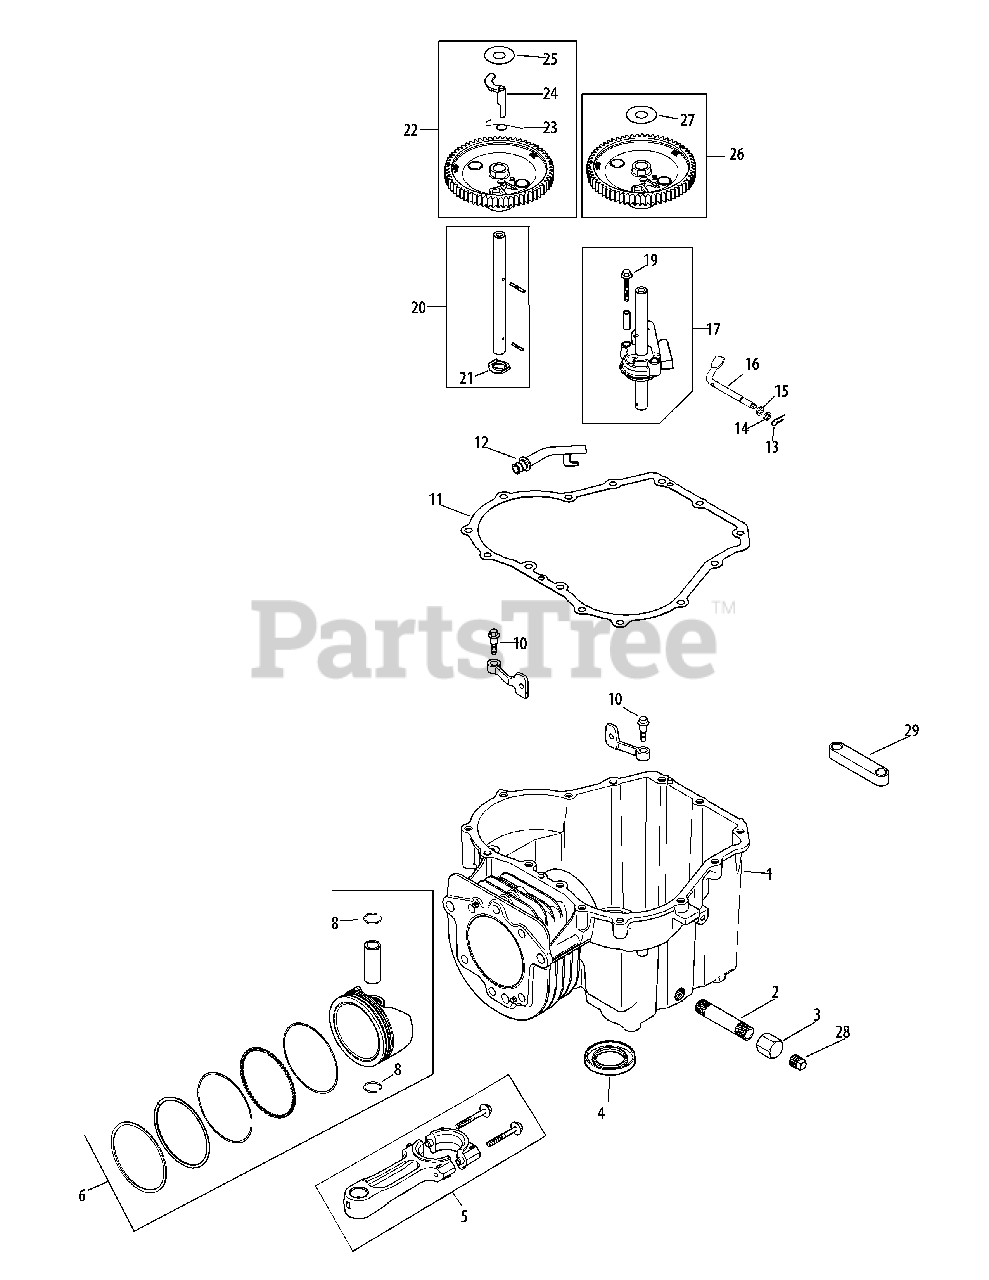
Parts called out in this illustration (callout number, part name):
1	Crankcase (Use: Short Block)
2	Not used in this application
3	Not used in this application
5	Connecting Assembly Rod
6	Piston w/ Ring Set, 94mm (Incl. 8)
8	Piston Pin Retainer
10	Shd. Thd. Frm. Screw, M6 X 1 X 26
11	Gasket
12	Drainback Tube
13	Hitch Pin Clip
14	Flat Washer, 6 Mm
15	Flat Washer, 1/4
16	Governor Cross Shaft
17	Oil Pump Ass’y Kit (Incl. 19)
19	Oil Pump Screw
20	Cam Center Shaft Kit (Incl. 21)
21	Thrust Washer
22	Camshaft Ass’y Kit (Incl. 23-25)
25	Thrust -Acr. Washer
26	Camshaft Ass’y Kit (Incl. 27)
27	Thrust -Acr. Washer
28	Square Head Pipe Plug, 3/8
29	Not used in this application
